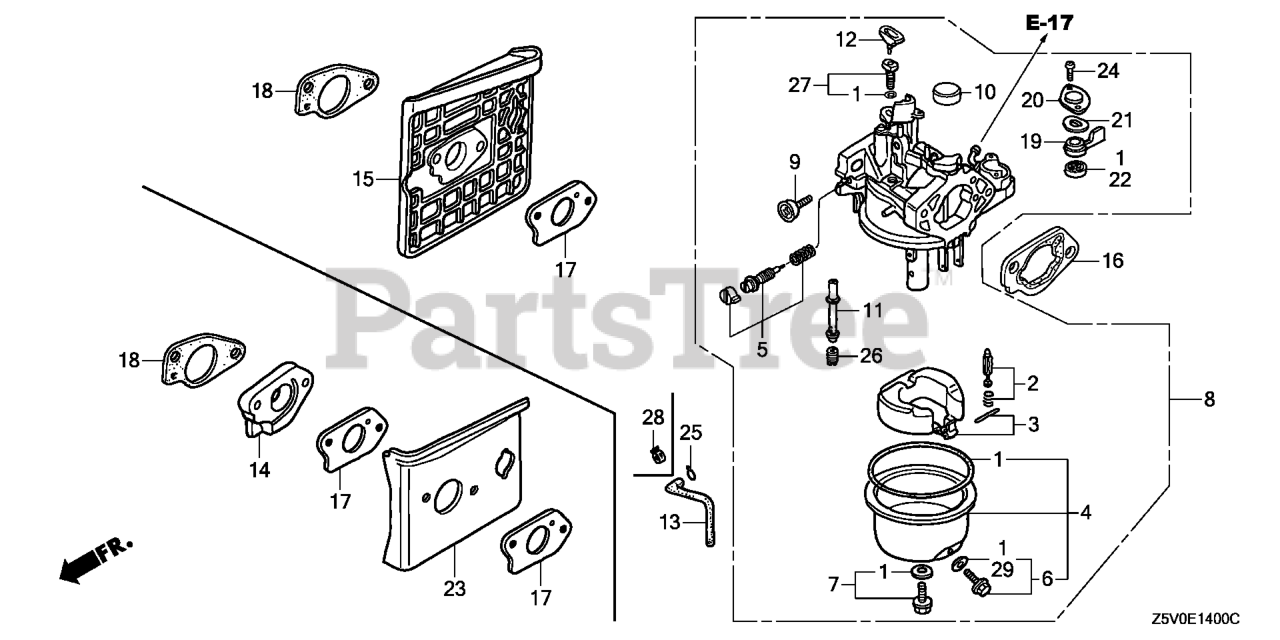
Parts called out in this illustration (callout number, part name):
1	GASKET SET (EXC. 16173-001-004) (CARBURETOR NO.) (EXCEPT 16173-001-004)
2	VALVE SET, FLOAT
3	FLOAT SET (CARBURETOR NO.)
4	CHAMBER SET, FLOAT
6	SCREW SET, DRAIN (Honda Code 1672187). (CARBURETOR NO.)
7	SCREW SET
8	CARBURETOR ASSY. (BE81P A)
9	SCREW, THROTTLE STOP
10	CAP, CHOKE LEVER DUST
11	NOZZLE, MAIN
12	COLLAR, SET
13	TUBE, AIR VENT (75MM)
15	INSULATOR, CARBURETOR
16	SPACER, CARBURETOR
17	GASKET, CARBURETOR
18	GASKET, INSULATOR
19	LEVER, VALVE
20	PLATE, LEVER SETTING (CARBURETOR NO.)
21	SPRING, PETCOCK LEVER (CARBURETOR NO.)
22	GASKET, VALVE
24	SCREW, PAN (3X6)
25	CLIP, TUBE (B8)
26	JET, MAIN (#95)
26	JET, MAIN (#98) Use from Engine SN BE87A A to BE87A A.
26	JET, MAIN (#100) Use from Engine SN BE87A A to BE87A A.
27	JET SET, PILOT (#45) (CARBURETOR NO.)
29	WASHER, PLAIN (6.2X10.7 DRAIN) (CARBURETOR NO.)
